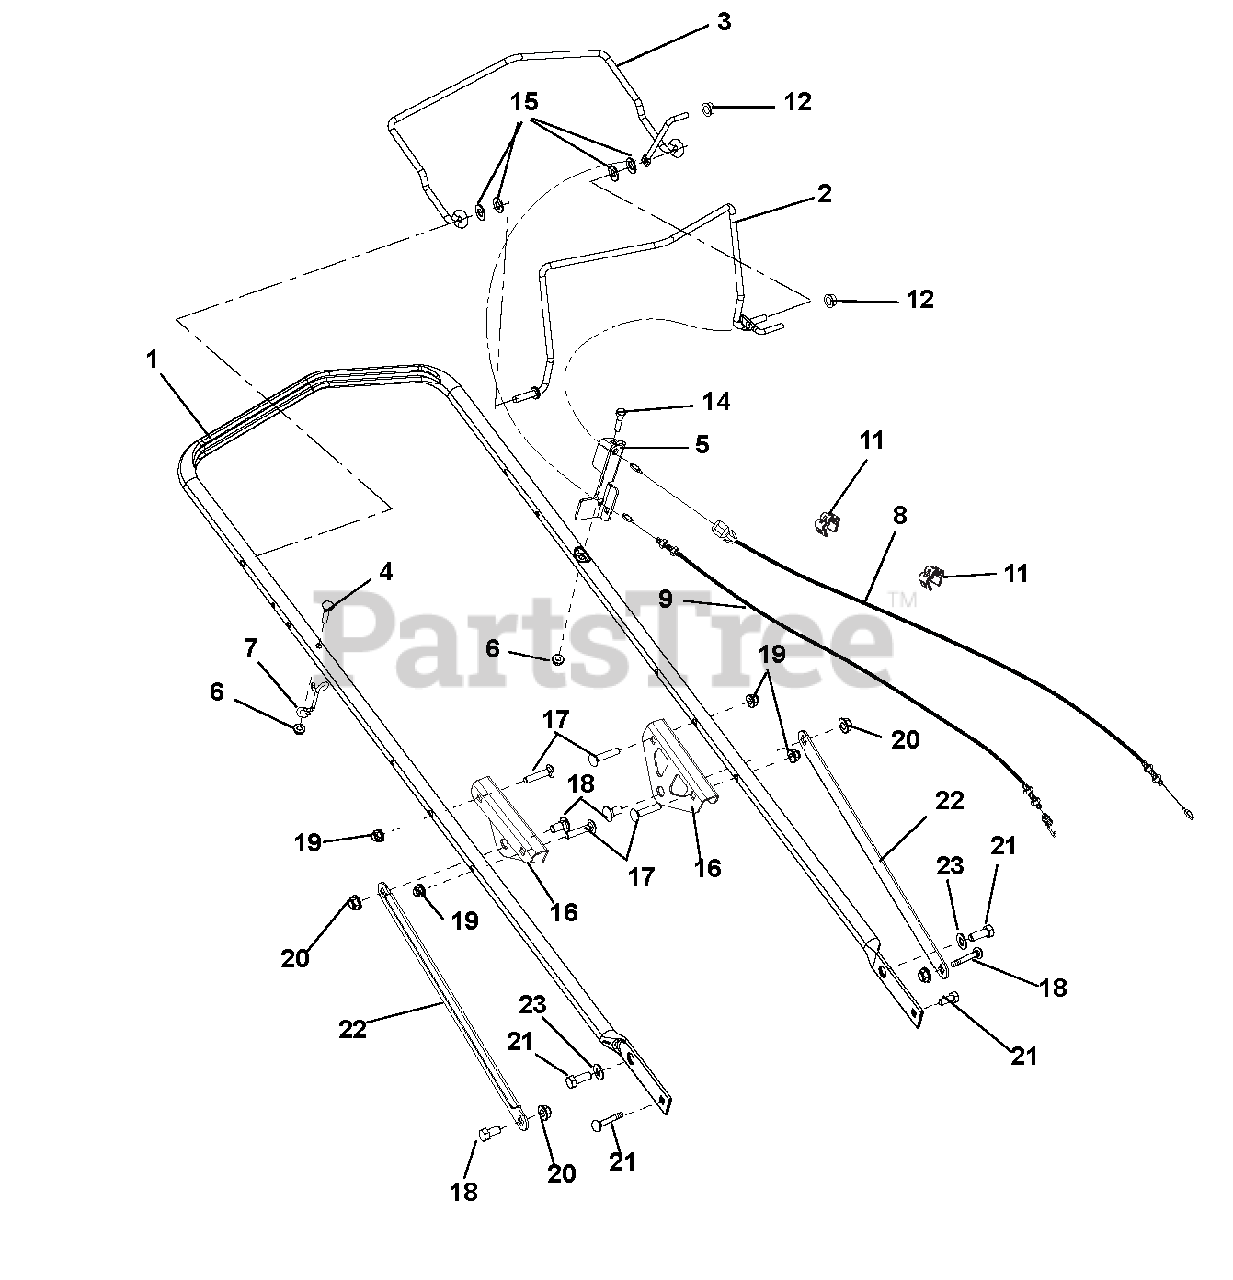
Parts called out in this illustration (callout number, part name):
1	HANDLEBAR, XD21 - 2010
2	WLDMT, OPC BAIL - COMM 21
3	WLDMT, TRACTION BAIL - COMM 21
4	BLT-RDHDXLSQNK.25-20X1.25 G5ZC
5	ANCHOR, CABLE
6	@NUT-LK-TOP-FLG .25-20 YWZC
7	GUIDE - PULLCORD
8	CABLE, ENGINE - ADJUSTABLE
9	CABLE, COMMERCIAL 21 TRACTION
10	@BLT-HEX .31-18X.75 GR5 YWZC
11	CONDUIT CLIP
12	PUSH NUT, .25
13	PLATE,HINGE
14	@BLT-HEX .25-20X1.25 GR5 YWZC
15	@WSHR-FL-STL.344X.688X.065YWZC
16	BRKT, HANDLEBAR REINFORCEMENT
17	@BLT-RDHDSQNK .31-18X1.50 G5YZ
18	@BLT-RDHDSQNK .38-16X.75 G5YZ
19	@NUT-LK-NYL-FLG .31-18 YWZC
20	@NUT-LK-NYL-FLG .38-16 YWZC
21	@BLT-HEX .38-16X.75 GR5 YWZC
22	STRAP,HANDLEBAR
23	@WSHR-FL-STL.406X.812X.065 YWZ
